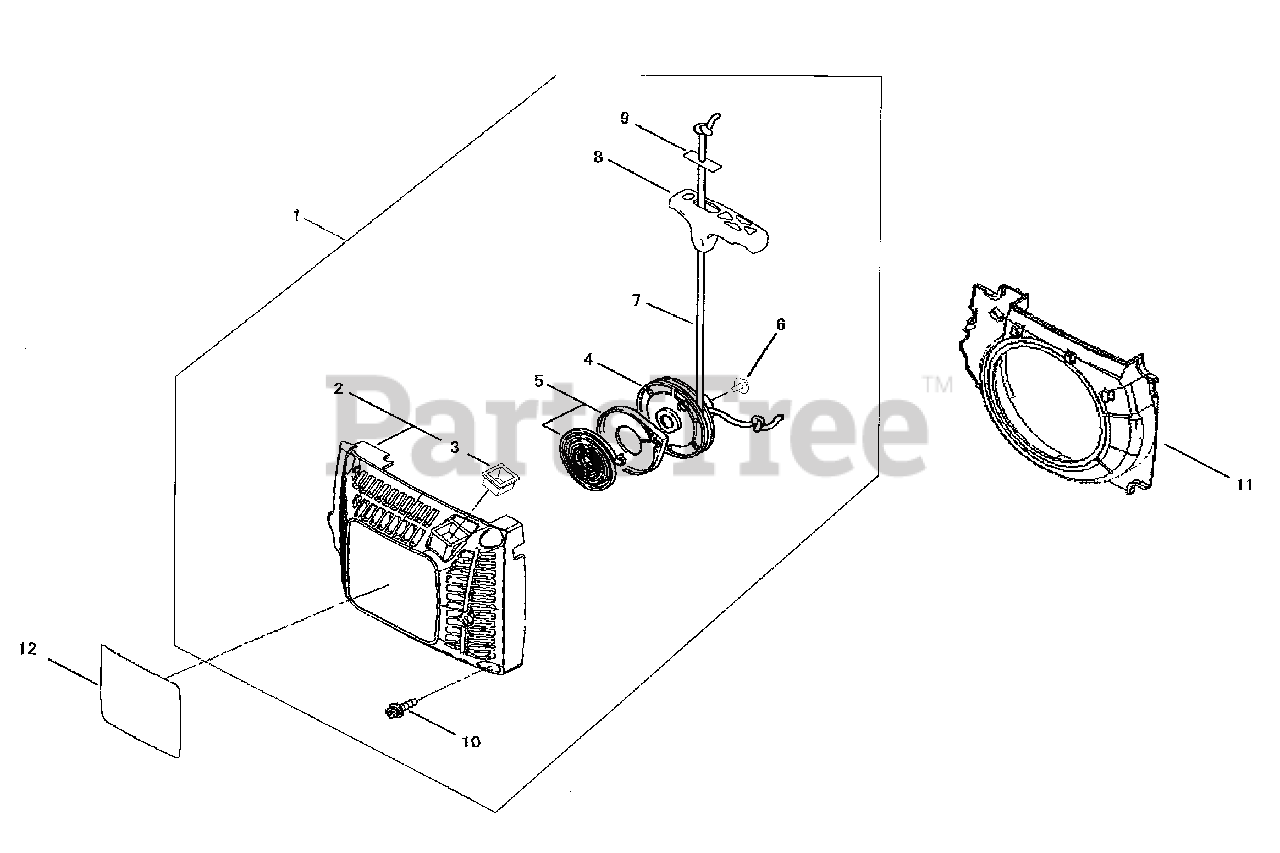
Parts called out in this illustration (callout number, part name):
1	STARTER ASSY, RECOIL
2	COVER
3	GUIDE, ROPE
4	REEL
5	RECOIL SPRING W/CASE
7	ROPE, STARTER
8	GRIP, STARTER
9	RETAINER, ROPE
10	BOLT M4×16
11	PLATE, AIR
12	LABEL, MODEL - 490
